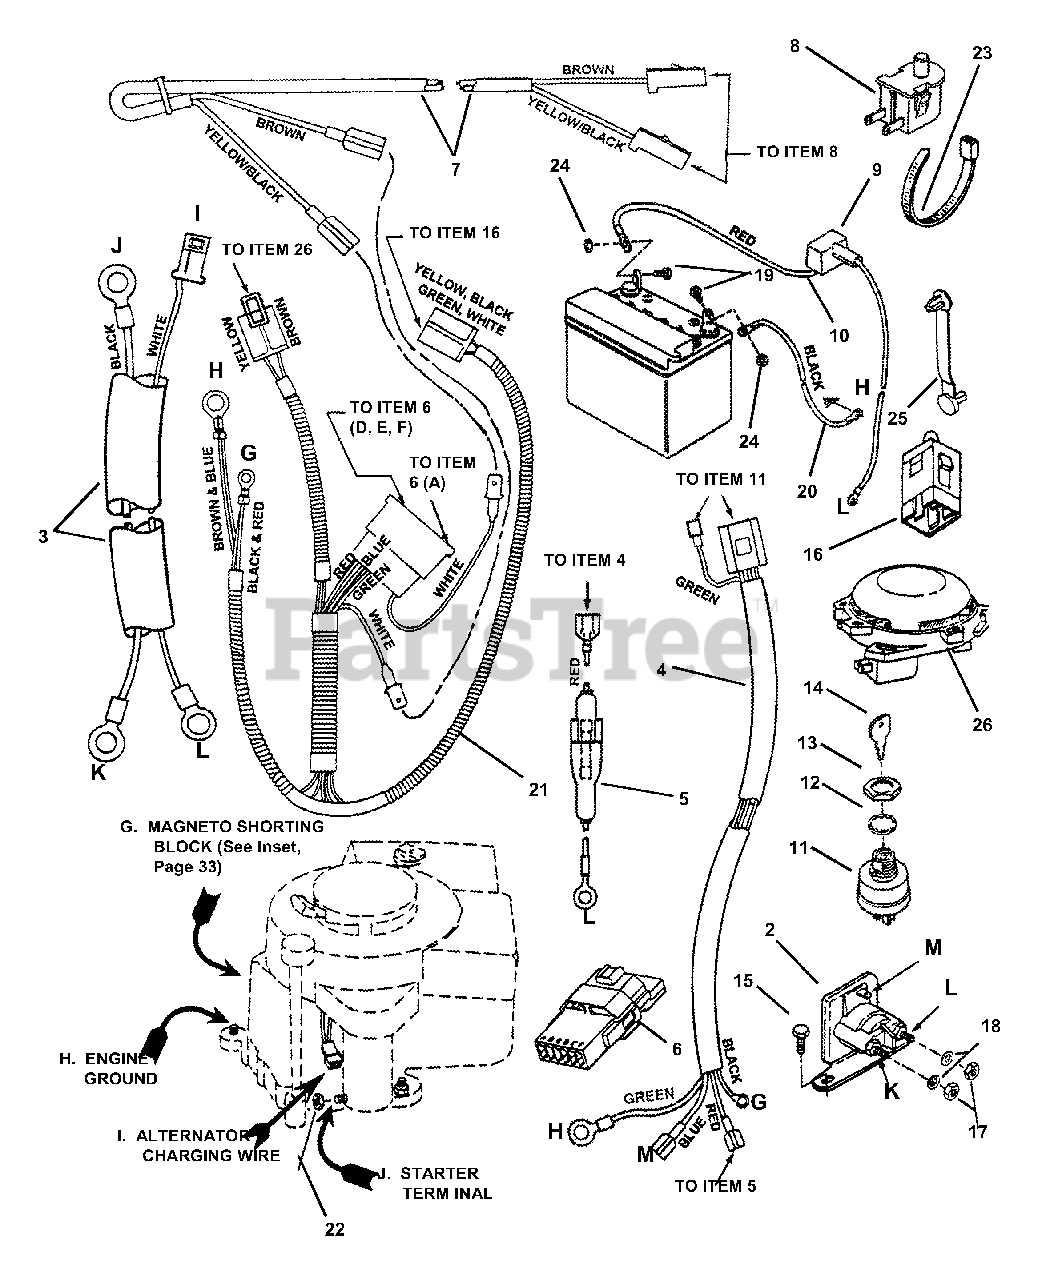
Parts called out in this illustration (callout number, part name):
1	KIT, Battery, 12V, U-1-7RS, 220CCA Dry Charge Snapper No Spill
2	SOLENOID
3	HARNESS, Starter Wiring (Briggs)
4	HARNESS, Ignition Wiring (Briggs)
5	HOLDER, Fuse
6	INTERLOCK Module (Briggs)
7	HARNESS, (Deck Interlock Wiring)
8	SWITCH, Deck Interlock (NO)
9	COVER, Battery Cable
10	CABLE, Positive (Red)
11	SWITCH, Ignition
12	WASHER, 5/8" Internal Tooth Lock
13	NUT, 5/8-32 Hex
14	KEY, Switch
15	SCREW, 1/4-20 x 1/2" Hex Washer Self-Tap
16	SWITCH, Operator Presence Control (OPC) Traction (NC/NO)
17	NUT, 1/4-20 Hex, Grade 5 or B
18	WASHER, 1/4" Internal Tooth Lock
19	SCREW, 1/4-20 x 5/8" Hex Head Cap, Grade 5
20	CABLE, Negative
21	HARNESS, Operator Presence Control Wire
22	NUT, 1/4-20 Hex, Grade 5 or B
23	TIE, 7" Long Cable
24	NUT, 1/4-20 Hex Center Lock, Grade 5 or B
25	TIE, 2" Long Cable
26	SWITCH, Seat (NC)
